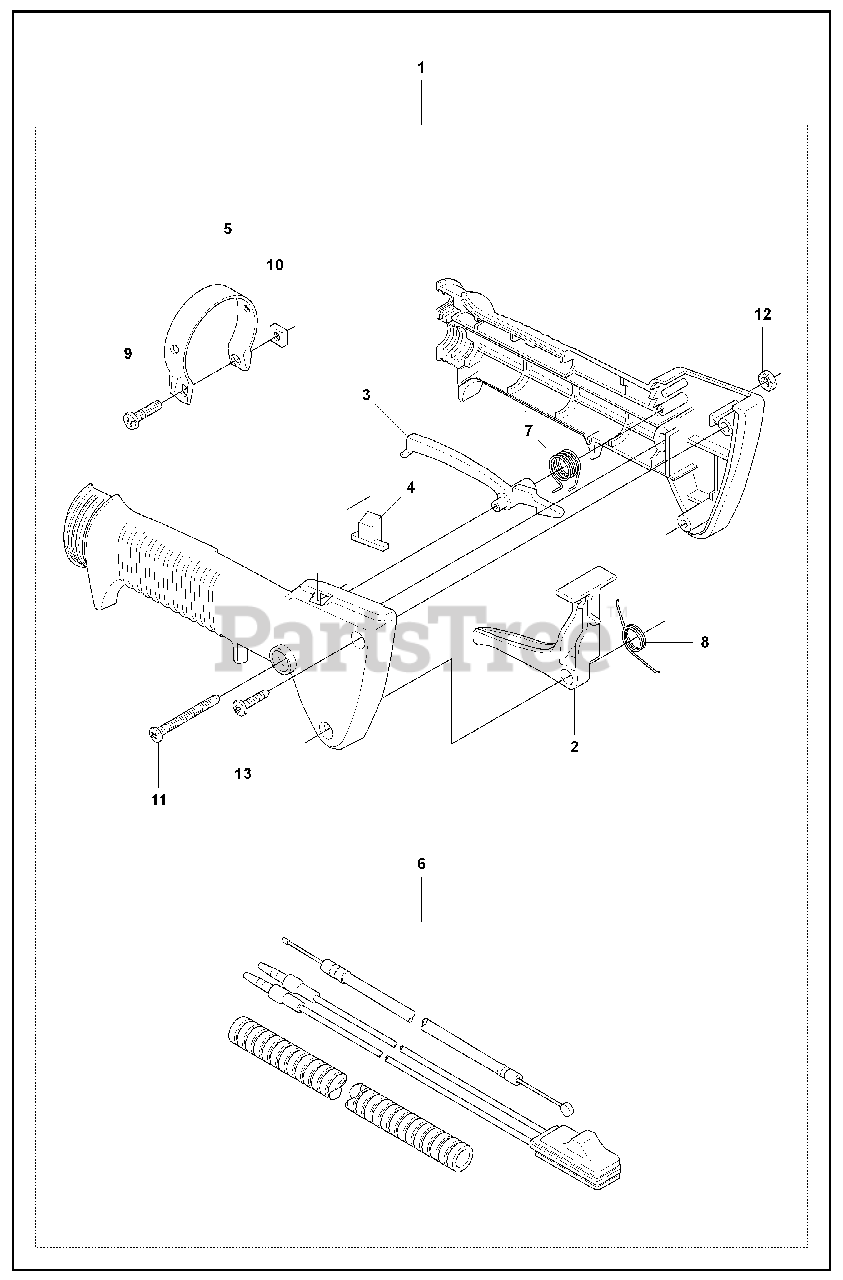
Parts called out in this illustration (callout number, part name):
1	LEVER ASSY
5	CLAMP
6	CABLE COMP.
9	SCREW
10	NUT
